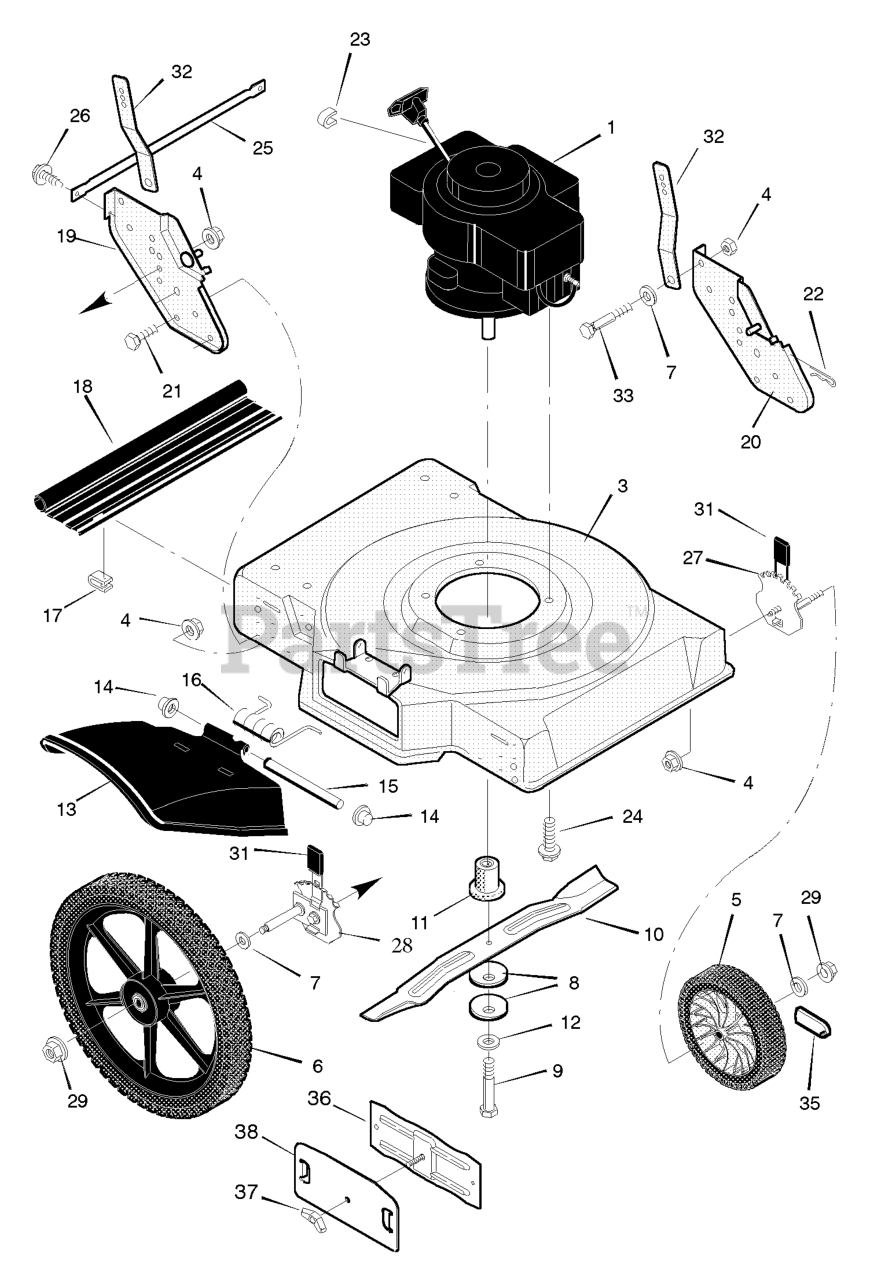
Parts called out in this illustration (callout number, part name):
1	Engine *
3	Housing
4	Nut, Hex
5	WHEEL & TIRE ASSEMBLY, White, 8"
6	Wheel and Tire, Rear (White)
8	Washer, Blade
9	Bolt, Hex
10	Blade - Mulcher
11	Blade Adapter
13	Deflector, Chute
14	Push On Cap
15	Pin, Pivot
17	Retainer
18	Deflector, Rear
19	Bracket, Right Wheel
20	Bracket, Left Wheel
21	Bolt, Hex
22	Pin, Hair
23	Stop, Rope
24	Bolt, Engine
27	Height Adjuster, Front
28	Height Adjuster, Rear
29	Locknut
32	Support, Handle
33	Bolt, Shoulder
35	Hub Cap
37	Wingnut
